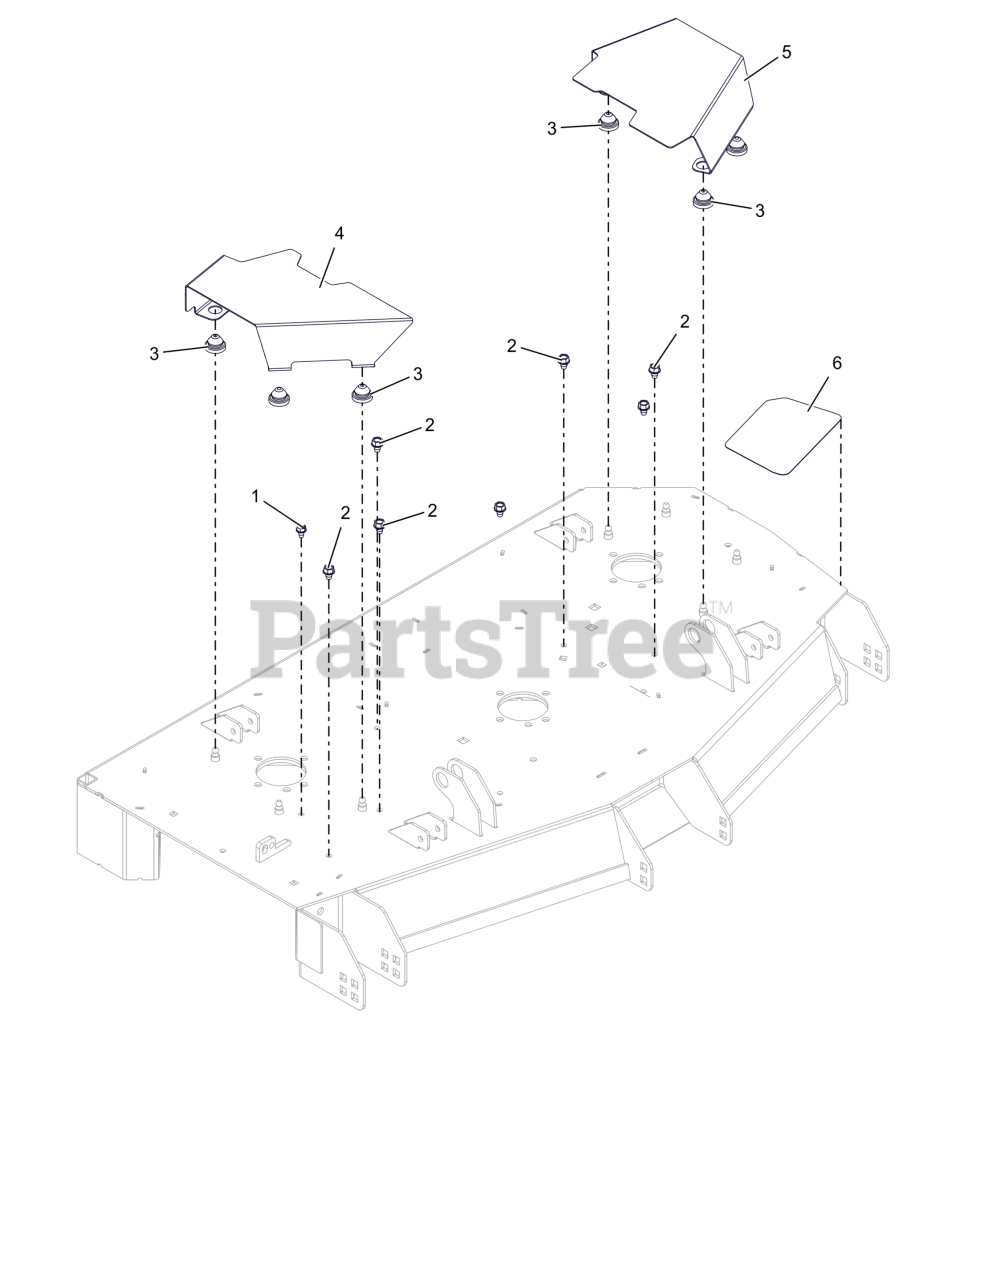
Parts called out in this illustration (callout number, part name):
1	SCR,TAP .312-18X.50 HWH TR ZCC
2	SCR,TAP .375-16X.50 HWH TR ZCC
3	COUPLING, RUBBER PUSH-IN
4	COVER- BELT 48" RIGHT
5	COVER- BELT 48" LEFT
6	GRIP, STEP ANTI SKID HD XF3
